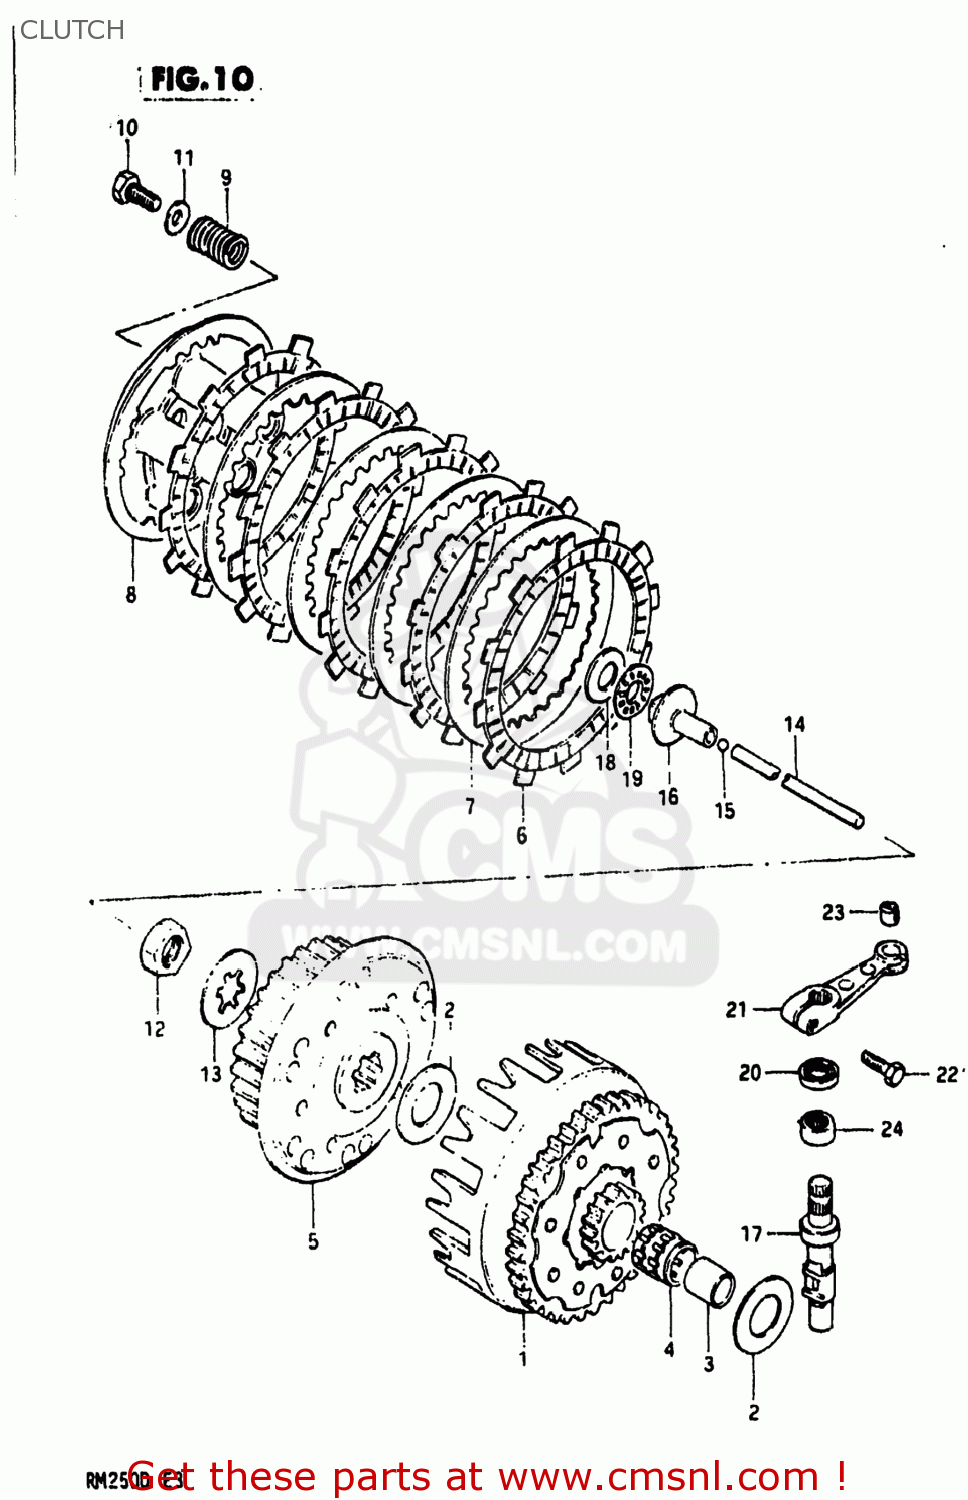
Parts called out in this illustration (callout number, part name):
1	GEAR ASSEMBLY,PRIMARY DRIVE
2	WASHER(20X38X2)
3	SPACER
4	ROLLER BEARING (25X30X2
5	HUB,CLUTCH SLEEVE
6	PLATE,CLUTCH DRIVE (MCA)
7	PLATE,CLUTCH DRIVEN (NAS)
8	DISC,CLUTCH PRESSURE
9	SPRING
10	BOLT, UPPER
11	WASHER
12	NUT (20MM)
13	WASHER,LOCK
14	ROD,CLUTCH PUSH
15	BALL
16	PIECE,CLUTCH PUSH
17	SHAFT,CLUTCH RELEASE C
18	WASHER
19	BEARING(15X28X2)
20	SEAL,OIL(12X19X5)
21	ARM,CLUTCH RELEASE
22	BOLT
23	PIECE,RELEASE ARM END
24	BEARING(12X19X12)
